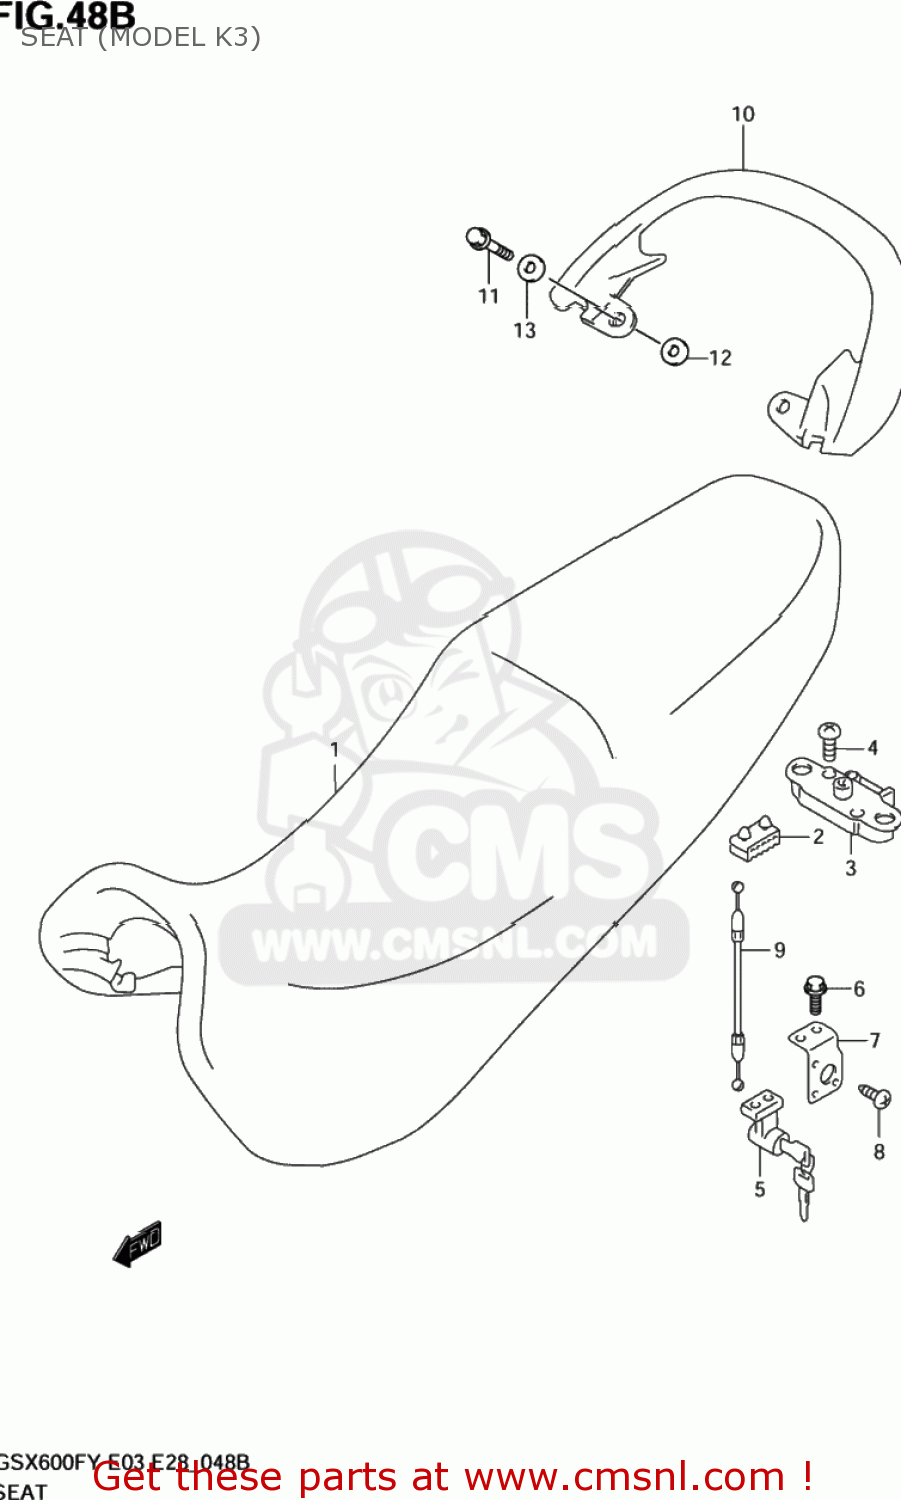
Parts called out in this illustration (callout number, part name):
1	SEAT ASSY
2	CUSHION,SEAT(40X20X15)
3	BRACKET,SEAT SUPPORT,RIGHT
4	SCREW
5	LOCK SET,SEAT
6	BOLT
7	BRACKET,SEAT LOCK
8	SCREW
9	CABLE,SEAT LOCK
10	HANDLE,PILLION RIDER(BLACK)
11	BOLT.MUF SPRT F
12	CUSHION,RIDER HNDL(17X24X1.5)
13	WASHER(8.5X24X2.3)
